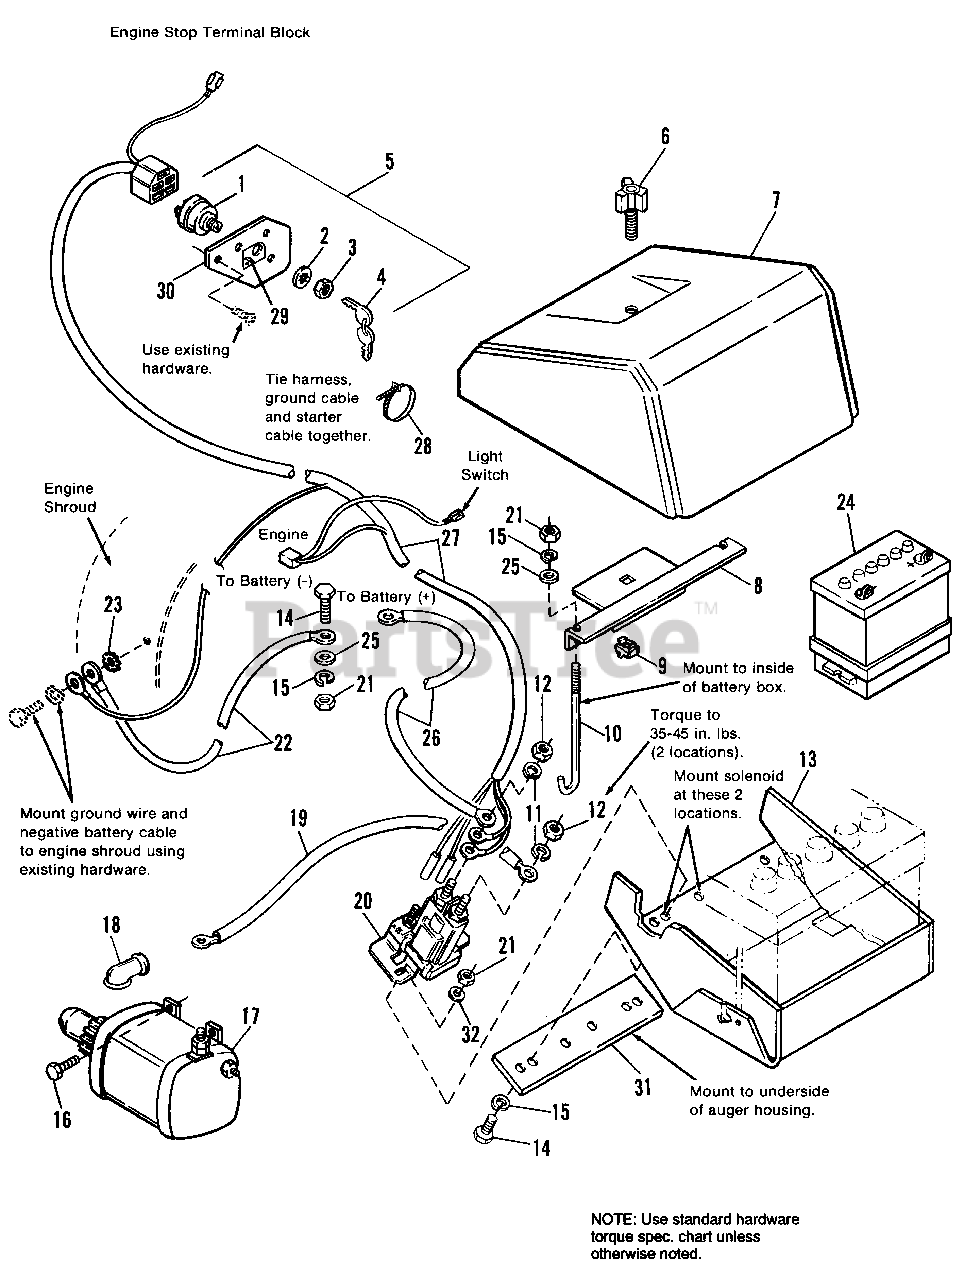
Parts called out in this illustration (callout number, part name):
2	LOCKWASHER, Int. Tooth, 5/8 (Zinc Pltd.)
3	NUT, Special
4	KEY, Set of Two
5	SWITCH, Key (Incl. Ref. Nos. 1, 2, 3 & 4)
8	HOLDDOWN ASSY., Battery
9	NUT, Cage, Tinnerman, 5/16-18
11	LOCKWASHER, 5/16 (Zinc Pltd.)
12	NUT, Hex, Full, 5/16-24 (Zinc Pltd.)
13	SUPPORT ASSY., Battery
14	CAPSCREW, Hex, 1/4-20 x 3/4 (Zinc Pltd.)
15	LOCKWASHER, 1/4 (Zinc Pltd.)
16	SCREW
17	MOTOR, Starter (not serviced)
18	COVER, Terminal
19	WIRE, Solenoid to Starter, 25"
20	SOLENOID
21	NUT, Hex, Full, 1/4-20 (Zinc Pltd.)
22	WIRE, Battery to Solenoid, 15"
23	LOCKWASHER, Ext. Tooth 5/16 (Zinc Pltd.)
24	BATTERY, (Not included with kit)
25	WASHER, Flat, 1/4
26	CABLE, Battery to Ground, 38"
27	HARNESS, Wiring
29	DECAL, Key Switch
30	BRACKET, Key Switch
31	PLATE, Reinforcement
32	WASHER, 1/4
